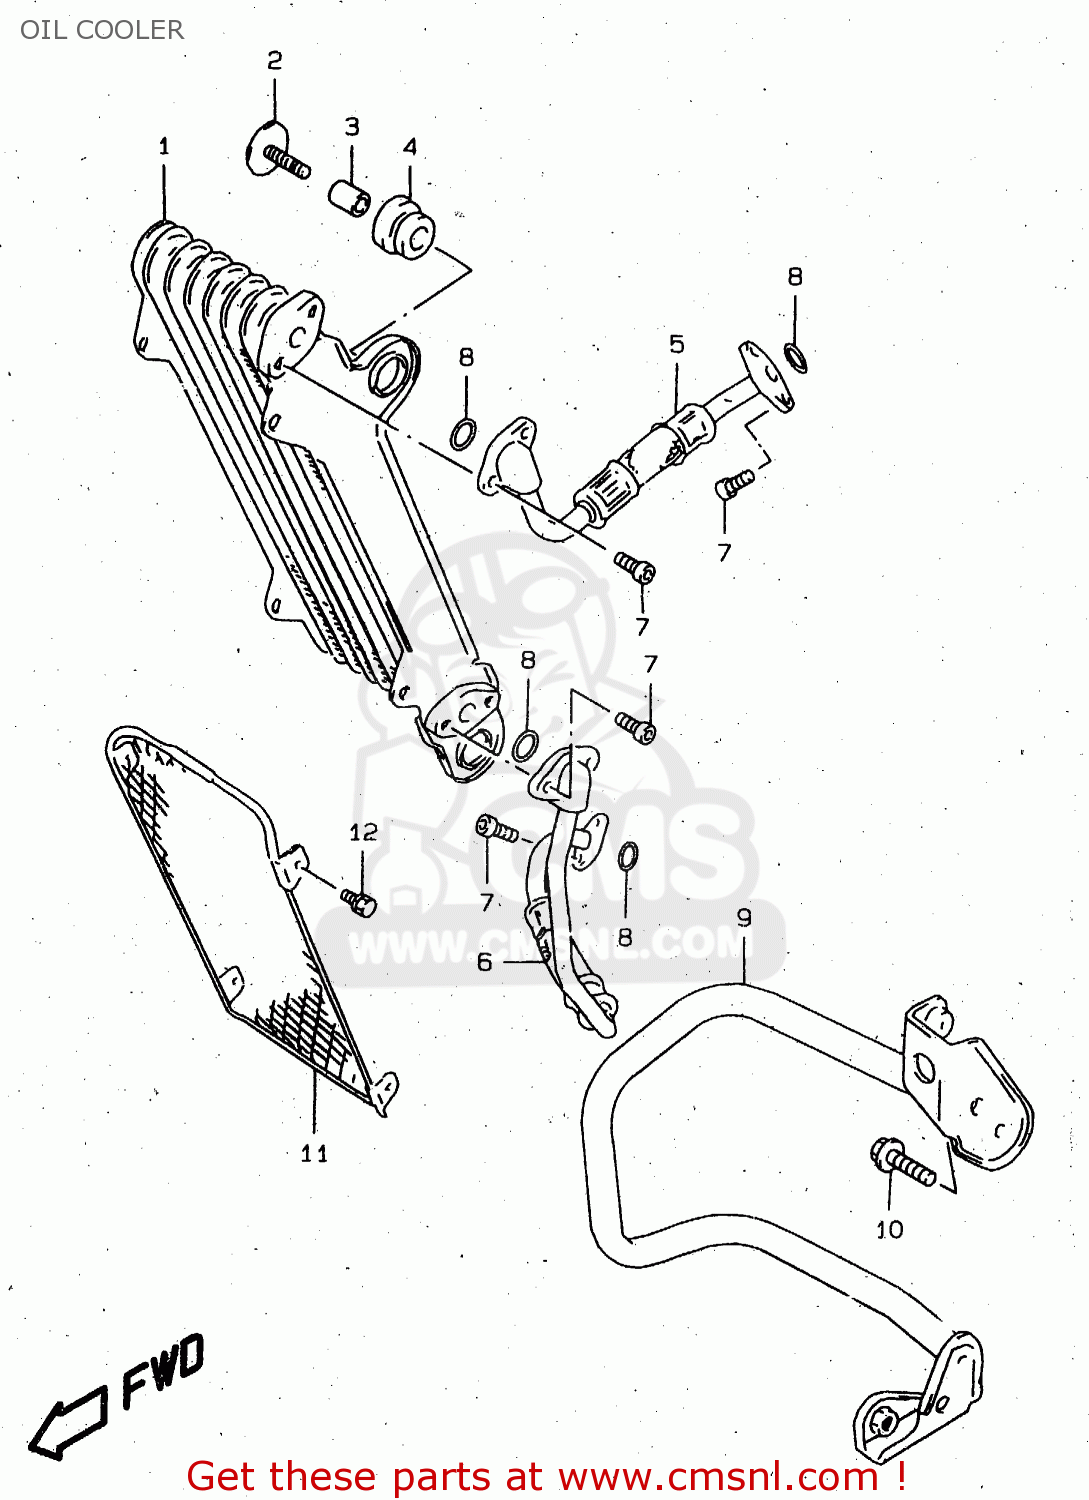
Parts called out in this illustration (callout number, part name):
1	COOLER ASSY,OIL
2	BOLT 8X28
3	SPACER(8.5X12X17)
4	CUSHION,OIL COOLER
5	HOSE,OIL COOLER UPR
6	HOSE,OIL COOLER LWR
7	BOLT
8	O RING(D:2.4,ID:12.3)
9	GUARD,OIL COOLER
10	BOLT
11	BUMPER,OIL COOLER
12	BOLT
